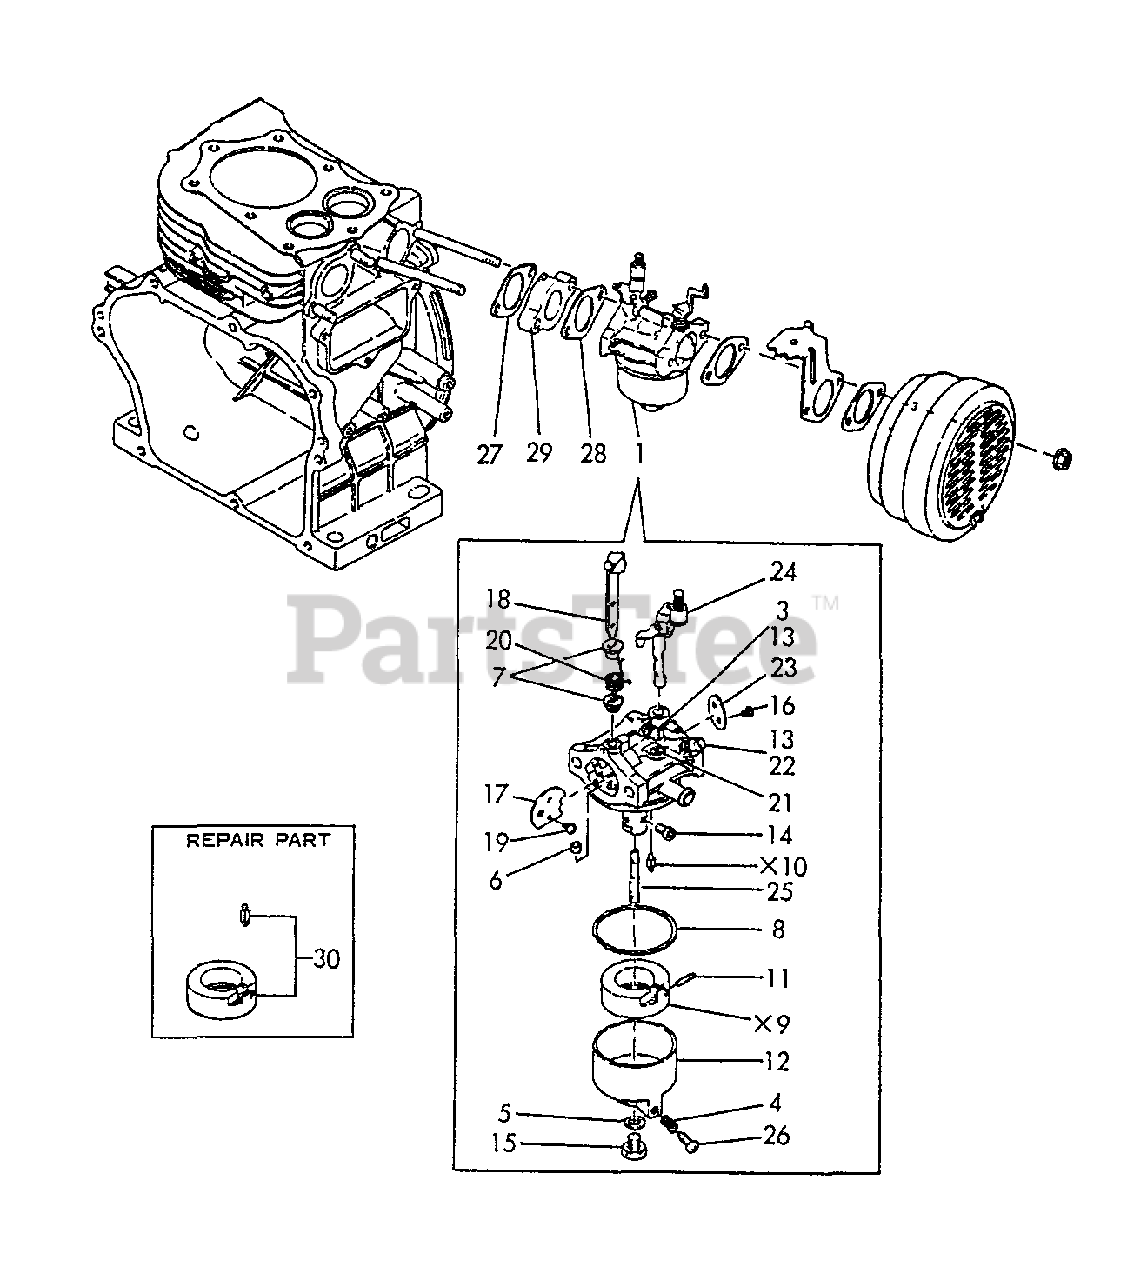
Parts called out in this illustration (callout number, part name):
1	CARBURETOR
3	SCREW, THROTTLE
6	RING, CHOKE SHAFT
7	RING, CHOKE LEVER
8	GASKET, FLOAT CHAMBER
9	FLOAT
10	NEEDLE
11	PIN
12	BODY
13	SPRING
14	JET, MAIN
15	BOLT
16	SCREW
17	VALVE, CHOKE
18	LEVER, CHOKE
20	SPRING, CHOKE
21	JET, PILOT
22	SCREW, PILOT
23	VALVE, THROTTLE
24	SHAFT, THROTTLE
25	NOZZLE, MAIN
26	SCREW
27	GASKET, SPACER
28	GASKET, INTAKE
29	GASKET, INTAKE
30	NEEDLE ASSY - RUBBER
